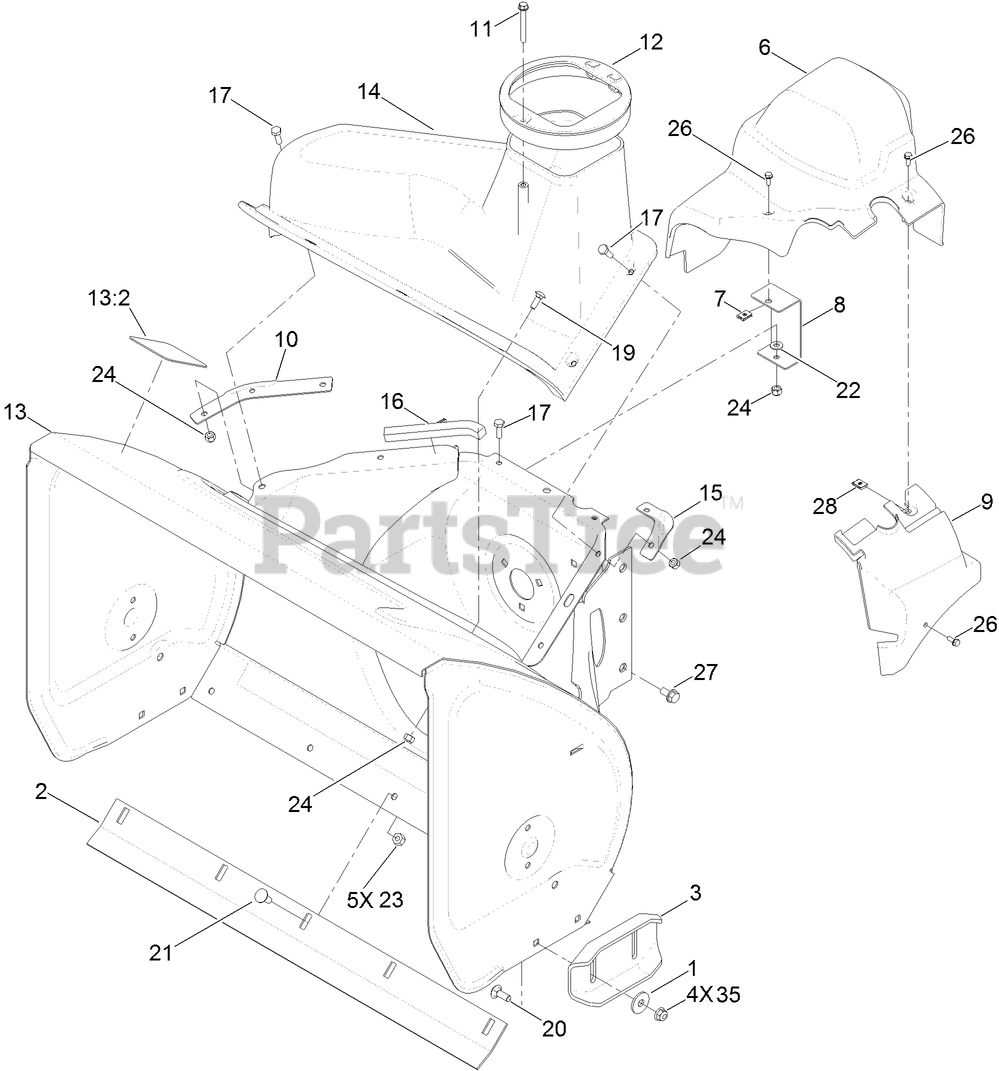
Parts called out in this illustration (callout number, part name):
1	WASHER
2	SCRAPER-FIXED
6	COVER-BELT
7	NUT-SPEED
8	BRACKET-COVER, CLIP NUT
9	COVER-EXTENSION, BELT
10	SEAL-FLANGE, COVER
11	SCREW-PLASTITE
12	GUIDE-CHUTE
13	HOUSING-AUGER, 28 INCH
13:2	DECAL-DANGER
16	SEAL-HOUSING
17	SCREW-HH
19	BOLT-CARR
20	SCREW-CARR
21	SCREW-CARR
22	WASHER-FLAT
23	NUT-LOCK, NI
24	NUT-LOCK, NI
26	SCREW-HWH
27	SCREW-HWHTF
28	NUT-SPEED
35	NUT-HF, NI
